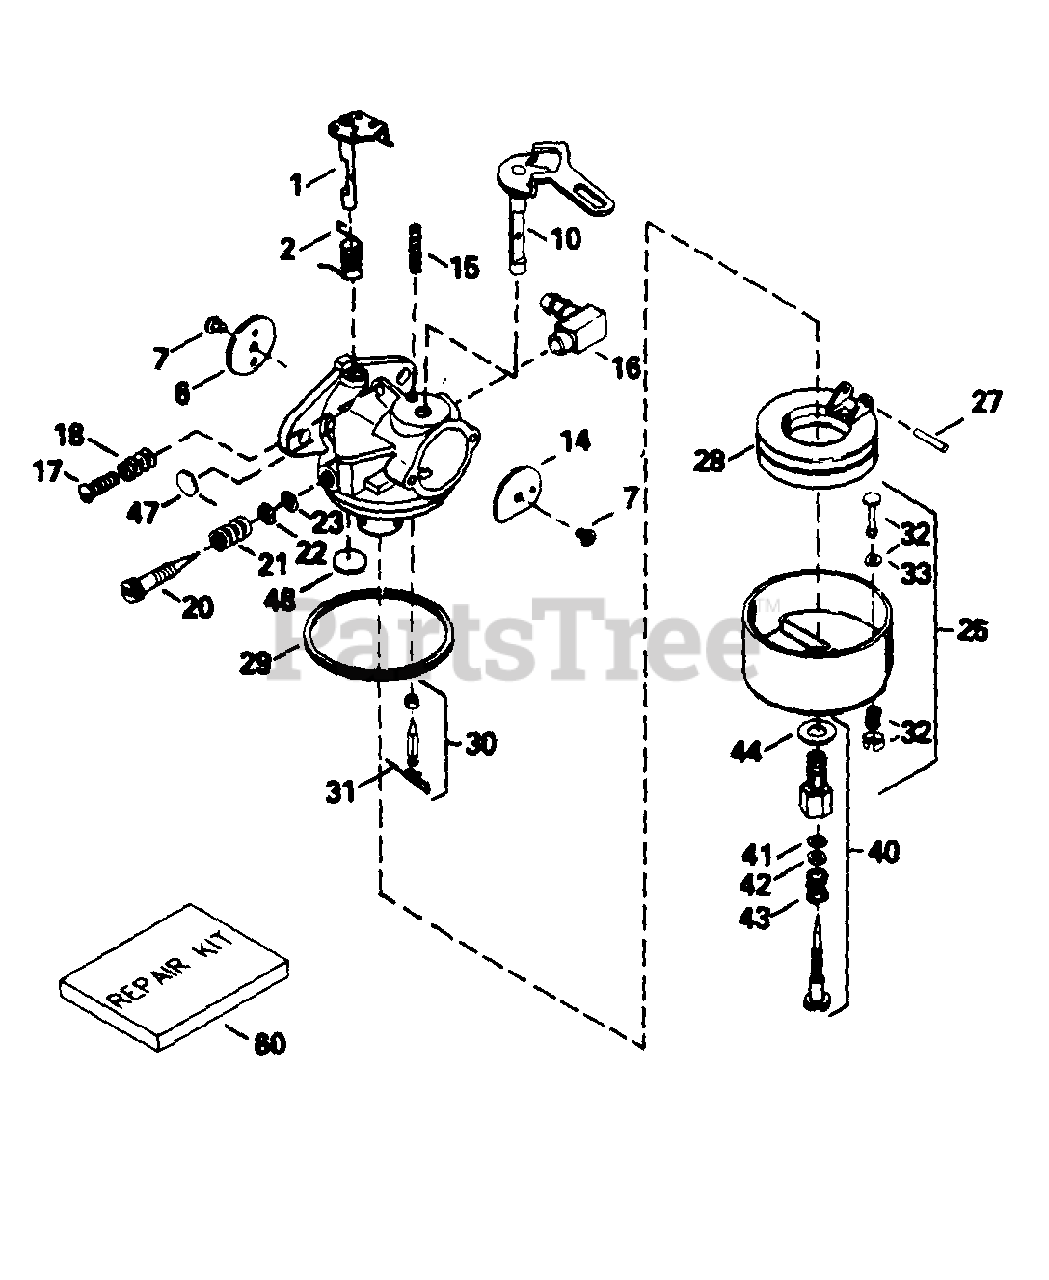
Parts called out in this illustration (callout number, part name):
1	Throttle Shaft & Lever Ass'y.
2	Throttle Return Spring
6	Throttle Shutter
7	Throttle & Choke Shutter Screw
10	Choke Shaft & Lever Ass'y.
14	Choke Shutter
15	Choke Positioning Spring
16	Fuel Fitting
17	Idle Speed Screw
18	Tension Spring
20	Idle Mixture Screw
21	Idle Tension Spring
22	Washer, Idle Screw
23	O-Ring, Idle Screw
25	Float Bowl Ass'y.
27	Shaft, Float
28	Float
29	O-Ring, Float Bowl to Body
30	Inlet Needle, Seat & Clip
31	Spring Clip
32	Bowl Drain Ass'y.
33	Drain Plunger Gasket
40	Main Adj. Screw Ass'y.
41	O-Ring, High Speed Mixture Screw
42	Washer, High Speed Mixture Screw
43	Tension Spring, High Speed Mixture Screw
44	Bowl Nut Washer
47	Welch Plug, Idle Mixture Well
48	Welch Plug, Atmospheric Vent
60	Repair Kit
